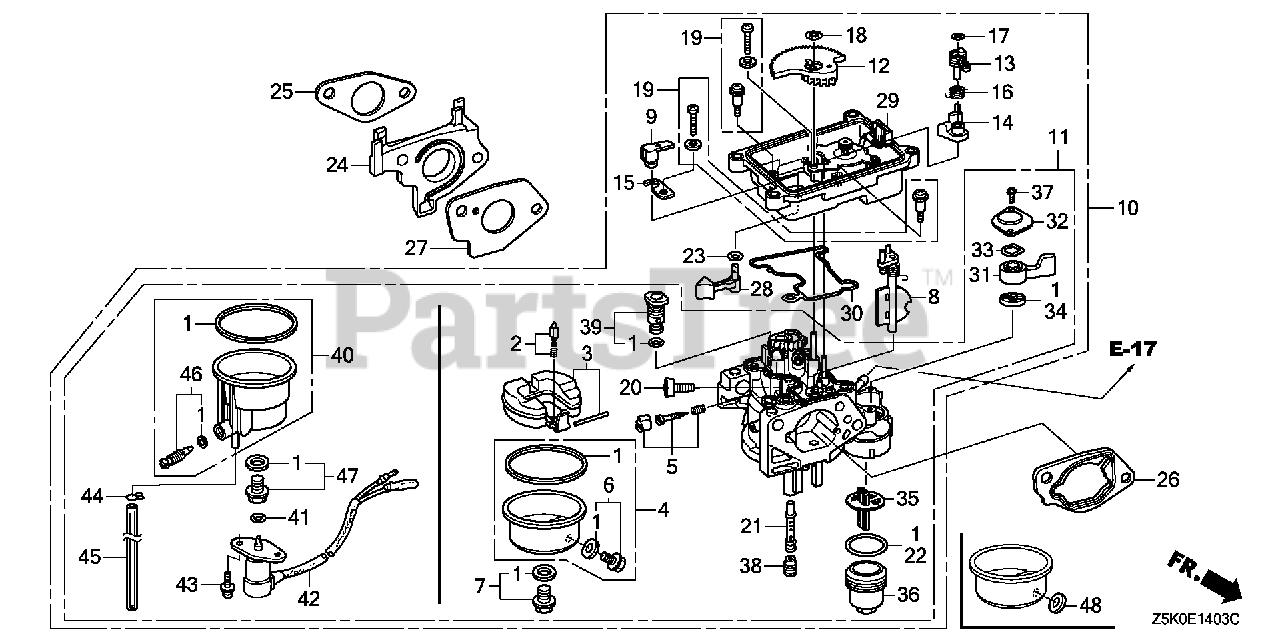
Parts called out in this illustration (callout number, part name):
1	GASKET SET (INCLUDES 16173-001-004)
2	VALVE SET, FLOAT
4	CHAMBER SET, FLOAT
5	SCREW SET, PILOT
6	SCREW SET, DRAIN
9	ARM, MANUAL START
10	CARBURETOR ASSY. (BE90B A)
11	CARBURETOR SET
12	GEAR, MIDDLE
13	ARM, CHOKE
14	LEVER, CHOKE CONTROL
16	SPRING, TORSION COIL
17	CLIP, SPECIAL
18	CLIP, SPECIAL
20	SCREW, STOP
21	NOZZLE, MAIN
22	GASKET, FUEL STRAINER CUP
24	INSULATOR, CARBURETOR
25	GASKET, INSULATOR
26	SPACER, CARBURETOR
27	GASKET, CARBURETOR
28	LEVER, MANUAL START
29	CASE, MOTOR
31	LEVER, PETCOCK
32	PLATE, LEVER SETTING
33	SPRING, PETCOCK LEVER
34	GASKET, PETCOCK
35	FILTER, CUP
36	CUP, FUEL STRAINER
37	SCREW, PAN (3X6)
38	JET, MAIN (#82)
38	JET, MAIN (#85)
38	JET, MAIN (#88)
39	JET SET, PILOT (#40)
48	WASHER, PLAIN (6.2X10.7 DRAIN)
